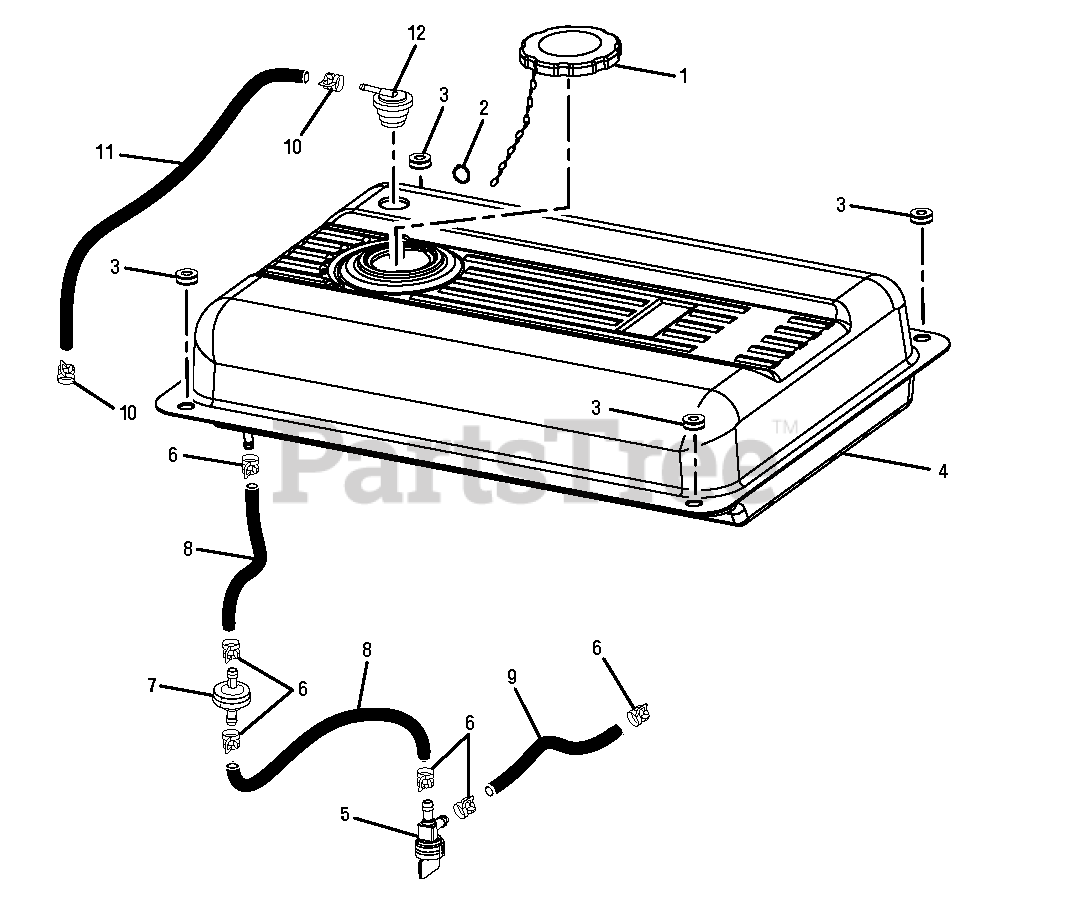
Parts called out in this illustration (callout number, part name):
1	FuelTank Cap
2	Ring Clip
3	Bushing w/lnsert
4	Fuel Tank
5	Fuel Valve
6	Fuel Une Clamp (1/2 in)
7	Fuel Line Filter
8	Fuel Une (1/4 in.)
9	Fuel Hose (1/4 in)
10	Fuel Line Clamp (7/16 in)
11	Vapor Hose
12	Vapor Vent
